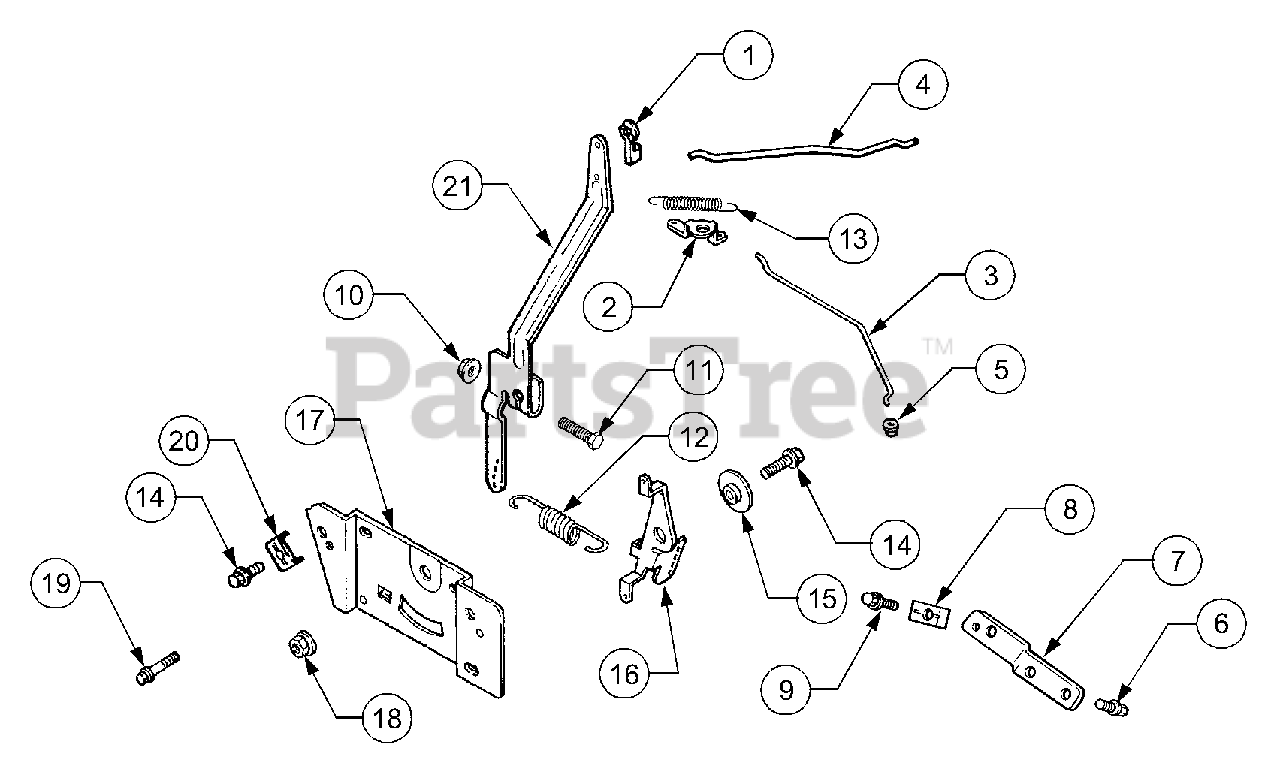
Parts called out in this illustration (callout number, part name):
1	Bushing, Throttle
2	Lever, Choke, Upper
3	Linkage, Choke, Upper
4	Linkage, Throttle
5	Bushing, Linkage
6	Screw, Bracket, M5 x .8 x 10
7	Bracket, Choke Mount
8	Clamp, Cable
9	Screw, Clamp, M5 x .8 x 16
10	Nut, M6 x 1
11	Screw, Governor Arm, M6 x 1 x 25
12	Spring, Governor
13	Spring, Linkage
14	Screw, Throttle Cntrl, M5 x .8 x 16
15	Spacer, Throttle Control
16	Lever, Throttle Control
17	Plate, Control
18	Nut, Hex, M5 x .8
19	Screw, Control Plate, M6 x 1 x 20
20	Clamp, Cable
21	Lever, Governor
